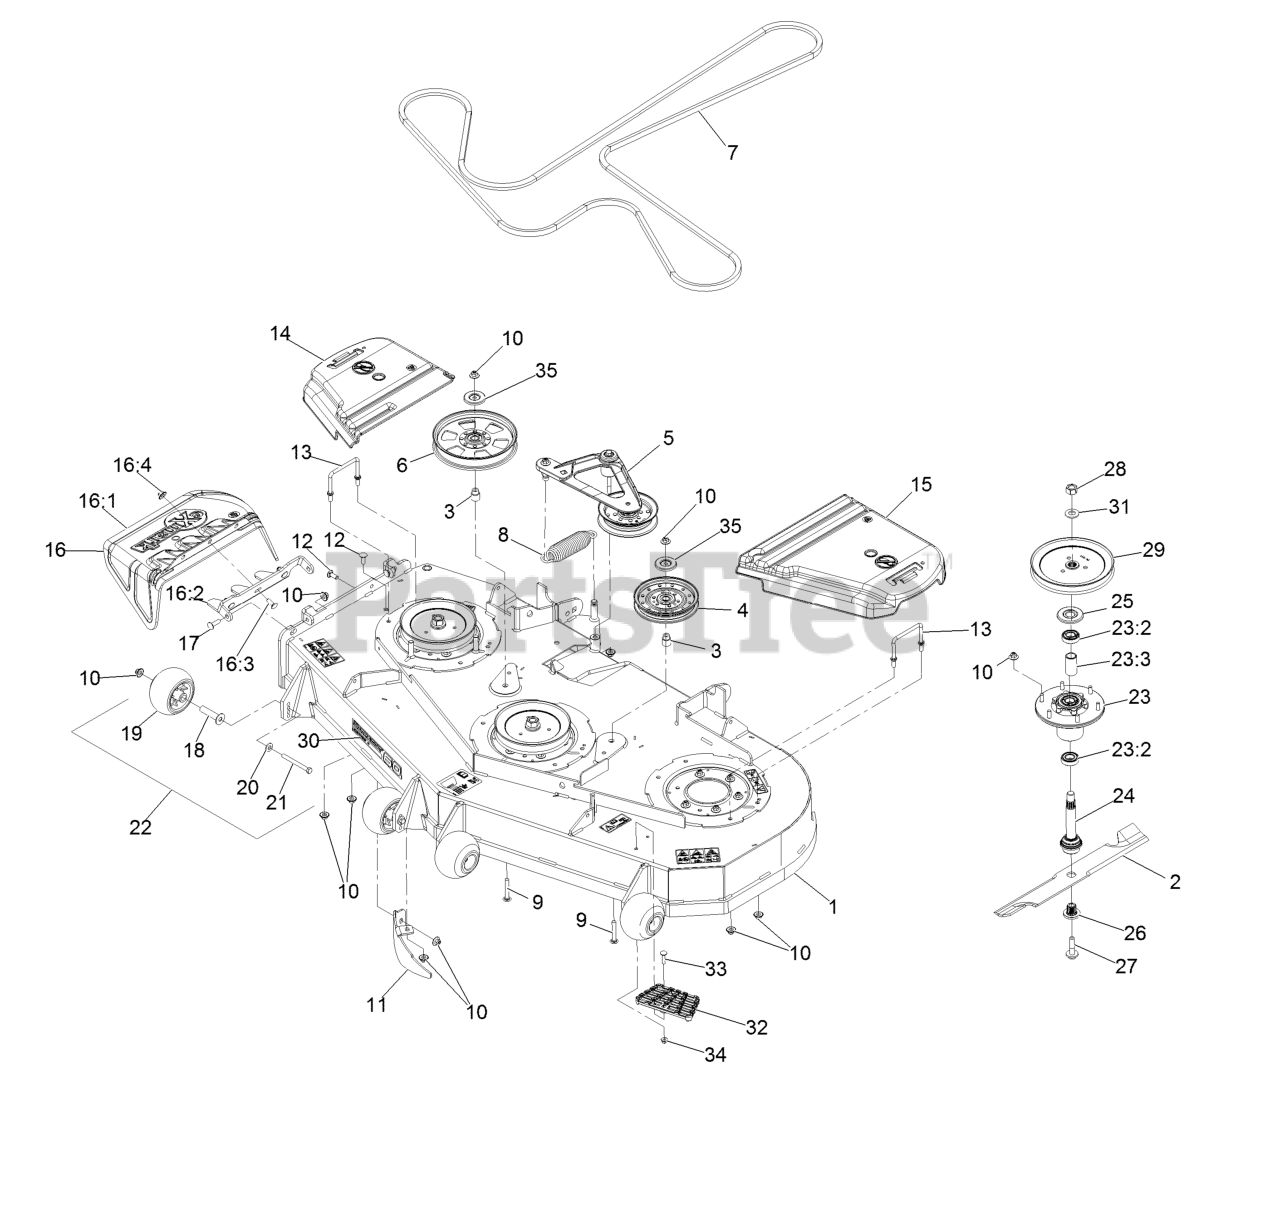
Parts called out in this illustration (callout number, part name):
1	Deck ASM,W/Decals 60
2	Blade, Solid
2	Blade, Low Lift
2	Blade, Mulching
2	Blade, Notched
2	Blade-Extreme 2, 20.50"
3	Bushing, Idler
4	Idler-Pulley
5	Deck Idler ASM
6	Pulley-Idler, Flat
7	Belt,V-5V-198.75
8	Spring-Extension
9	Bolt-Carriage 3/8-16 X 2 1/2
10	Nut-Nyloc 3/8-16 Flg
11	Dogleg - Lz60
12	Bolt-Carriage 3/8-16 X 1
13	Wireform-Cover
14	Cover-Belt, RH
15	Cover-Belt, LH
16	ASM,Discharge Chute
16:1	Chute, Discharge
16:2	Bracket,Discharge Chute
16:3	Bolt-Carriage 3/8-16 X 1
16:4	Nut-Nyloc 3/8-16 Flg
17	Bolt-Carriage 3/8-16 X 1 1/4
18	Axle, Roller
19	Roller-Anti-Scalp
20	Washer-Spring Disc 3/8
21	Screw-HH 3/8-16 X 3 3/4 GR 8
22	Kit, Anti-Scalp Roller
23	ASM-Cutter Hsg With Bearings
23:2	Bearing-Ball
23:3	Spacer-Bearing
24	ASM-Spindle And Seal
25	Guard,Bearing Top .989
26	Bushing, Splined
27	Screw-Sems 1/2-20 X 2.19
28	Nut-Hex
29	Sheave,Blade Drive 7.25
30	Decal, 604
31	Washer-Spring Disc 3/4
32	Step-Deck
33	Bolt-Carriage 5/16-18 X 1 1/4
34	Nut-Nyloc 5/16-18 Flg
35	Shield-Dust
